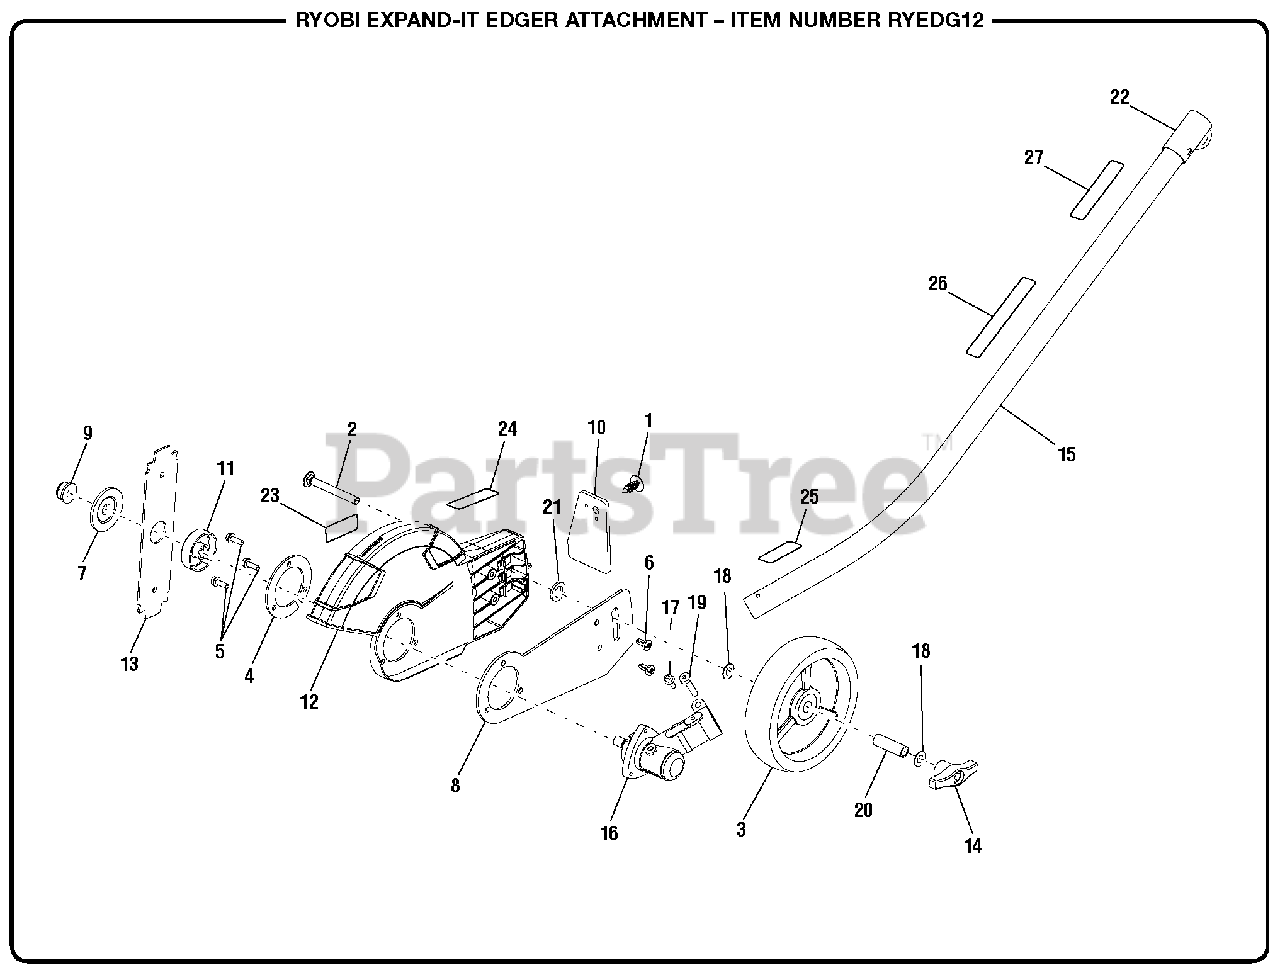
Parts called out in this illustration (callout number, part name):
1	Trim Clip
2	Carriage Bolt (M8 x 1.25 in.)
3	Wheel (dia150 mm)
4	Mounting Ring
5	Screw (M5 x 16 mm, T25 Torx Soc. Hd.)
6	Screw (10-14 x 1/2 in., T25 Torx Soc. Hd.)
7	Blade Washer
8	Main Bracket
9	Blade Lock Nut (M10 x 1.25 in.)
11	Flange Washer
12	Grass Shield Assembly
13	Blade (8 in., AC04215)
14	Adjusting Knob w/Hex Nut
15	Boom Assembly
16	Gear Case Assembly
17	Screw (10-24 x 5/8 in., Hex Soc. Hd.)
18	Washer (ID8.5 x OD20.5 x 2t)
19	Screw (1/4-20 x 1-1/4 in., Hex Soc. Hd.)
20	Axle Spacer
21	Washer (ID12 x OD20 x 2.5t)
22	Hanger Cap
23	Logo Label
24	Shield Icon Warning Label
25	Hot Surface Warning Label
26	Expand-It Label
27	Boom Icon Warning Label
